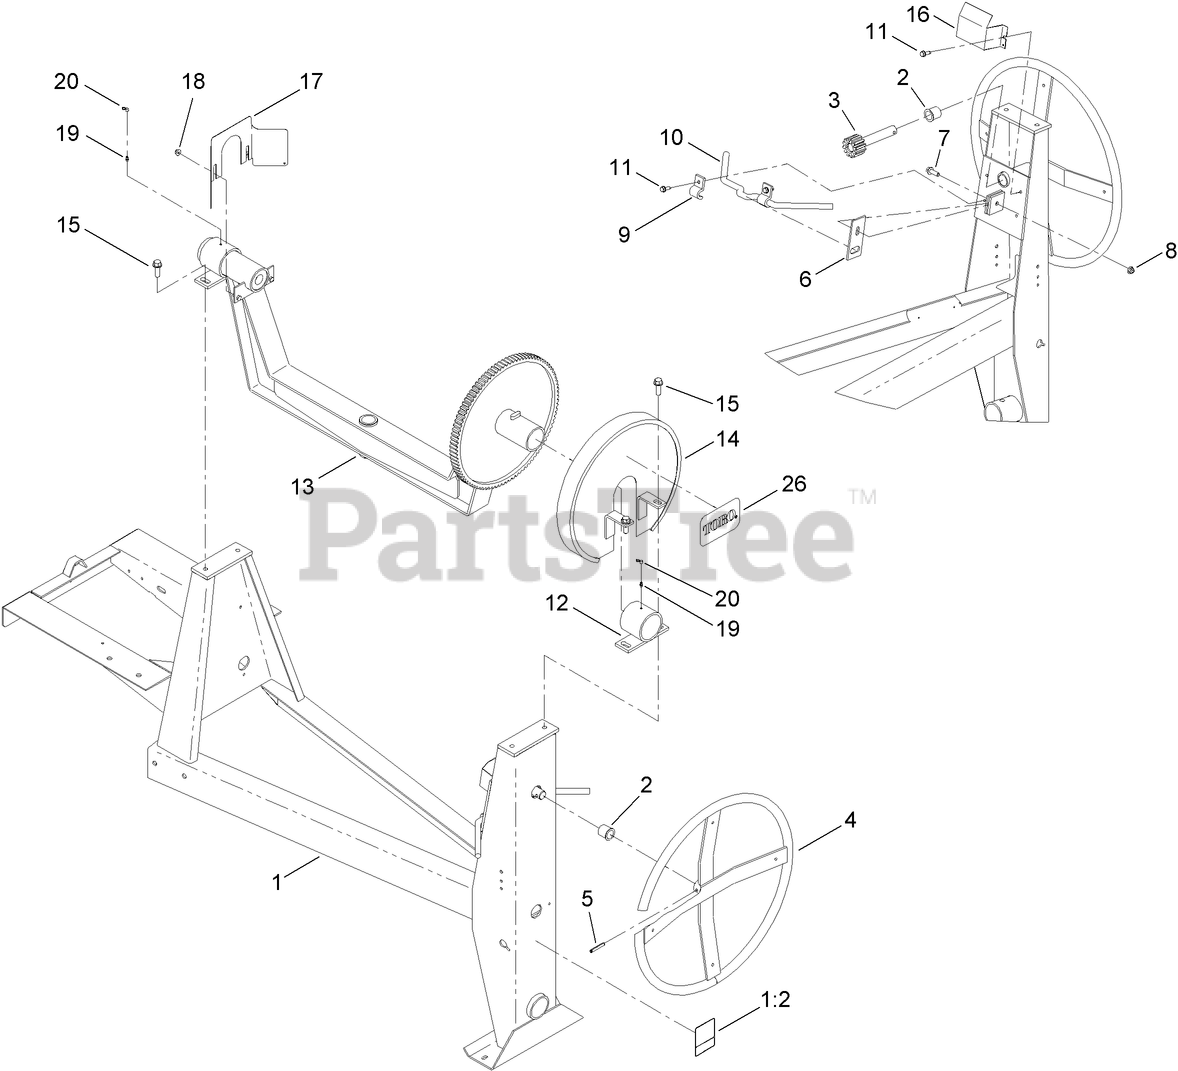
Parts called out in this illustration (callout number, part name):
1	FRAME ASM
1:2	DECAL-SAFETY CHAIN, TOWING
2	BUSHING-NYLON
3	SHAFT-TILT
4	HANDWHEEL
5	PIN-ROLL
6	DOG-BRAKE
7	SCREW-HHF
8	NUT-HF, NI
9	BRACKET-HANDLE
10	HANDLE-BRAKE
11	SCREW-HWHTF
12	TRUNNION
13	YOKE ASM
14	GUARD-BRAKE, UPPER
15	SCREW-HWH
16	GUARD-BRAKE, LOWER
17	GUARD-PINION
18	NUT-HF, NI
19	FITTING-GREASE
20	CAP-PLUG
26	DECAL
